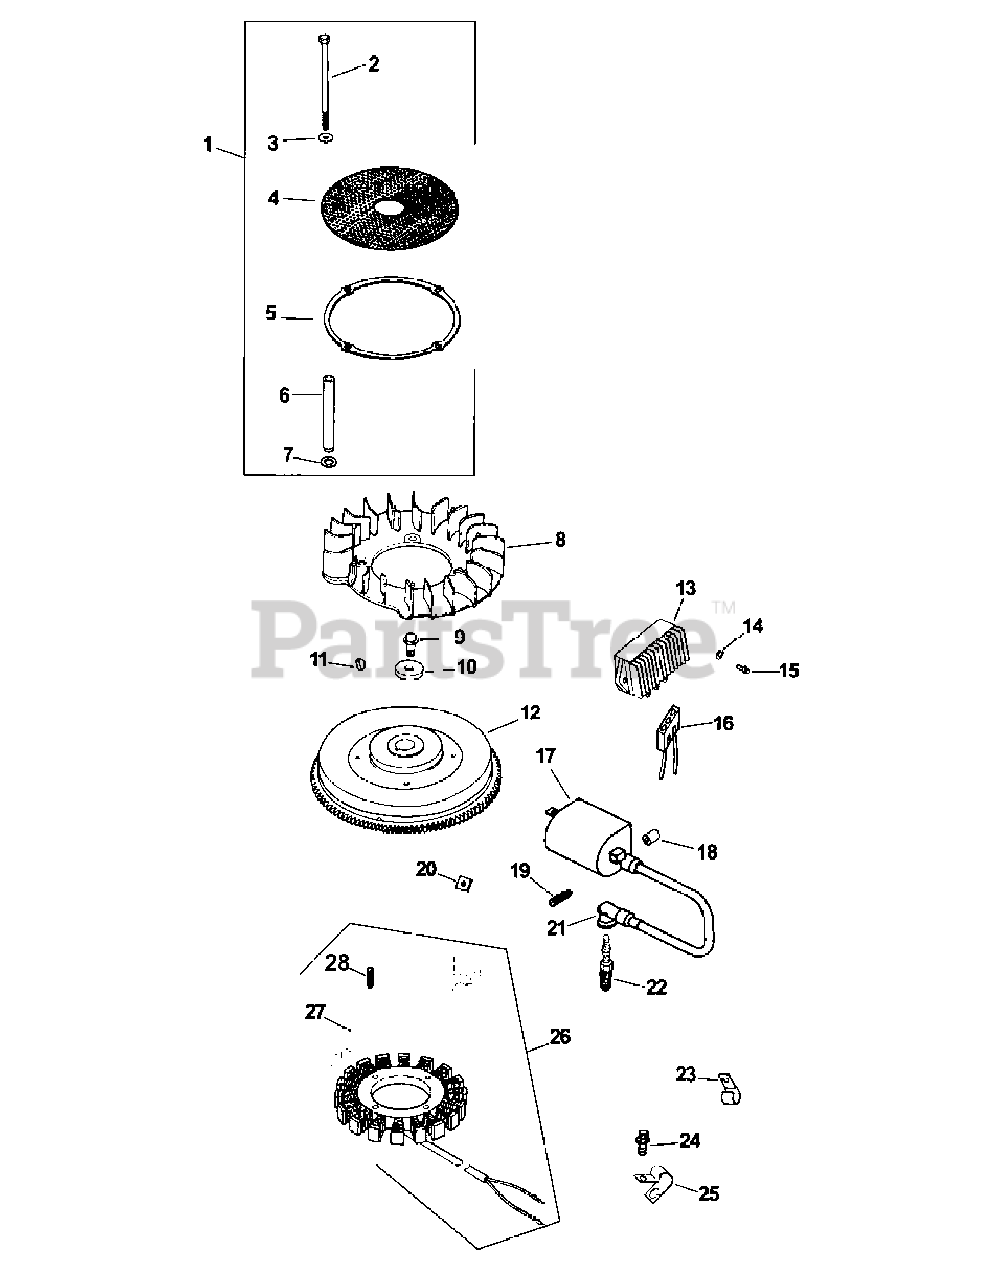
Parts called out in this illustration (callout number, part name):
1	Chopper Screen Kit
2	Hex Head Screw
3	Plain Washer
5	Support Ring
6	Grass Screen Spacer
7	Spring Washer
9	Hex Flange Screw
10	Plain Washer
12	Flywheel
13	Rectifier-Regulator
14	Plain Washer
15	Phillips Screw
17	Ignition Coil
19	Tapping Screw
21	Spark Plug Boot
22	Spark Plug
24	Hex Flange Screw
27	Stator Wire Bracket
28	Tapping Screw
